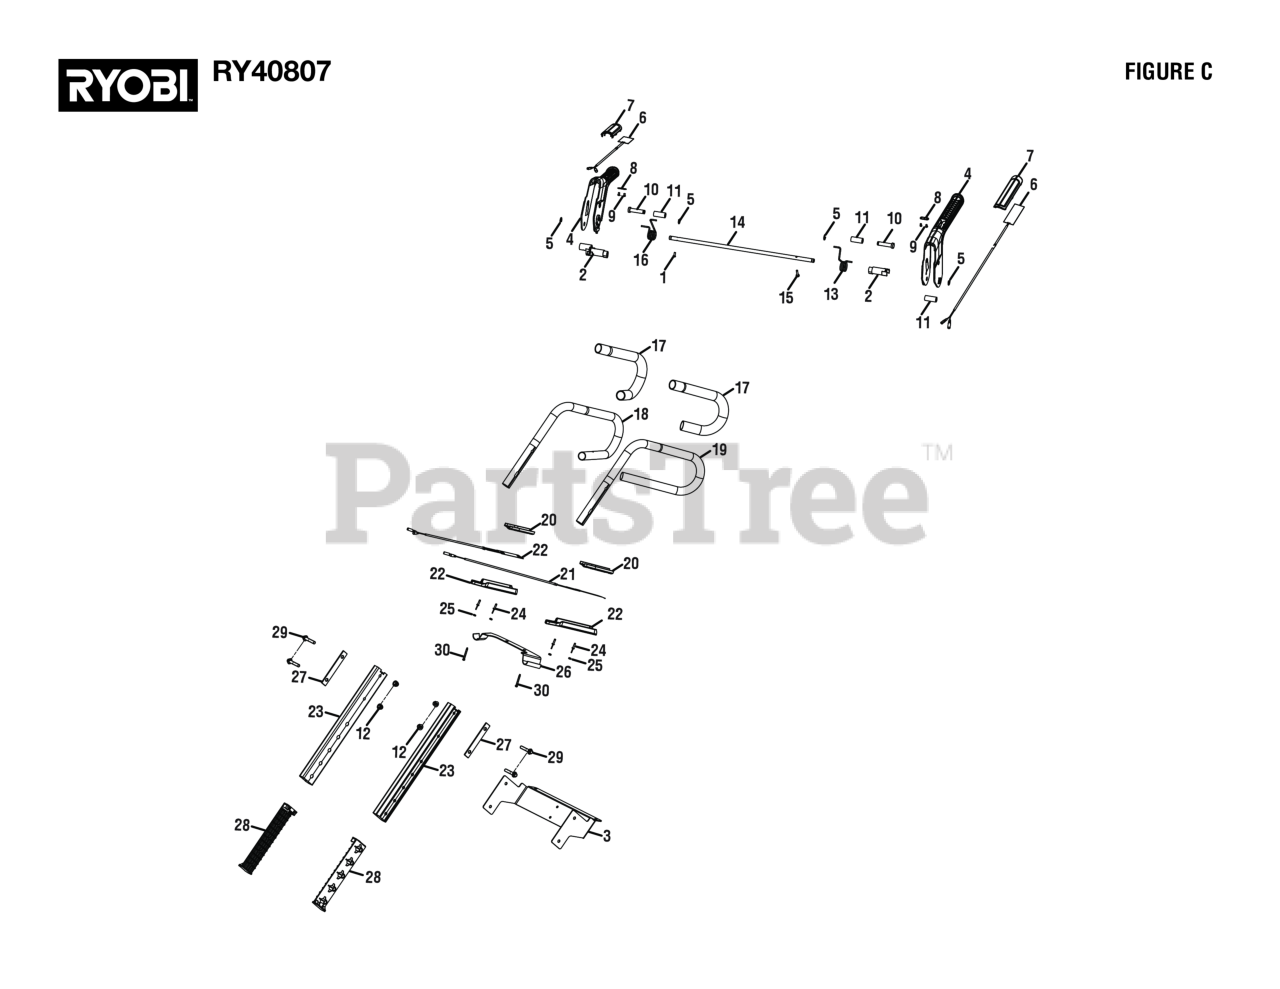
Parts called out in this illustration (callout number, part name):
1	Screw (M4 x 10 mm, Pan Hd.)
2	Rod Assembly
3	Console Support Bracket
4	Action Handle Paddle Assembly
6	Heating Grip
7	Heated Grip Snap Cover
9	Screw (M4 x 6 mm, T10 Torx Pan Hd.)
10	Paddle Stoper Pin
12	Lock Nut (M8 x 1.25 mm, Flange)
13	Drive Paddle Torsion Spring
14	Paddle Rod Grip
15	Bolt (M9 x 19 mm, T25 Torx Pan Hd.)
16	Drive Paddle Torsion Spring
17	Foam Tube
18	Handle (Right)
19	Handle (Left)
20	Lower Heated Grip
21	Heating Grips
22	Lower Heated Grip Assembly
23	Upper Handle Support Tube
26	Upper Handle Support
27	Handle Reinforcement Plate
28	Internal Bushing And Top Cover For Tube Assembly
29	Bolt (M8 x 45 mm, Hex Flange Hd.)
30	Screw (M4 x 38 mm)
